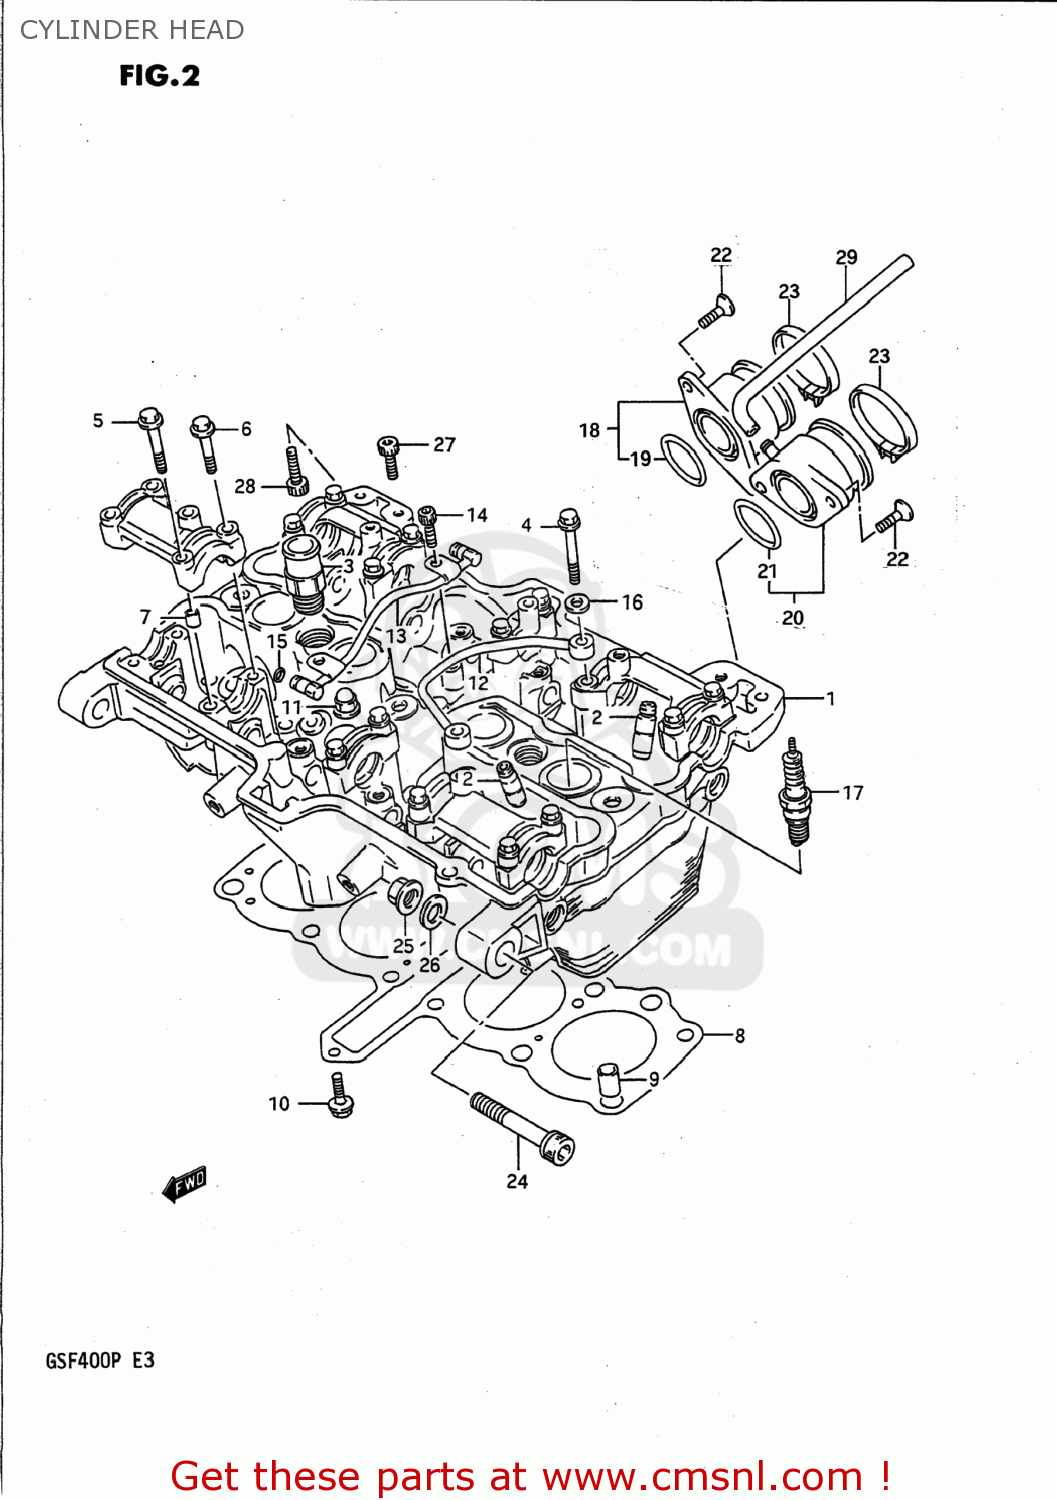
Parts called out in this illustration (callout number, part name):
1	HEAD ASSEMBLY,CYLINDER
2	GUIDE,VALVE
3	UNION,WATER HOSE
4	BOLT
5	BOLT(6X39)
6	BOLT(6X35)
7	PIN(6.2X8X11)
8	GASKET,CYLINDER HEAD (NAS)
9	PIN
10	BOLT
11	NUT 8MM
12	PIPE,OIL CYLINDER HEAD,L
13	PIPE,OIL CYLINDER HEAD
14	BOLT,STRANGER
15	O RING(D:1.9,ID:4.8)
16	WASHER, LOWER
17	PLUG,SPARK(CR9EK)
18	PIPE ASSY,INTAKE
19	O-RING
20	PIPE ASSY,INTAKE NO.2
21	O-RING
22	SCREW(6X16)
23	CLAMP
24	BOLT
25	NUT (10MM)
26	WASHER(10.5X20X3.2)
27	BOLT
28	BOLT
29	HOSE
